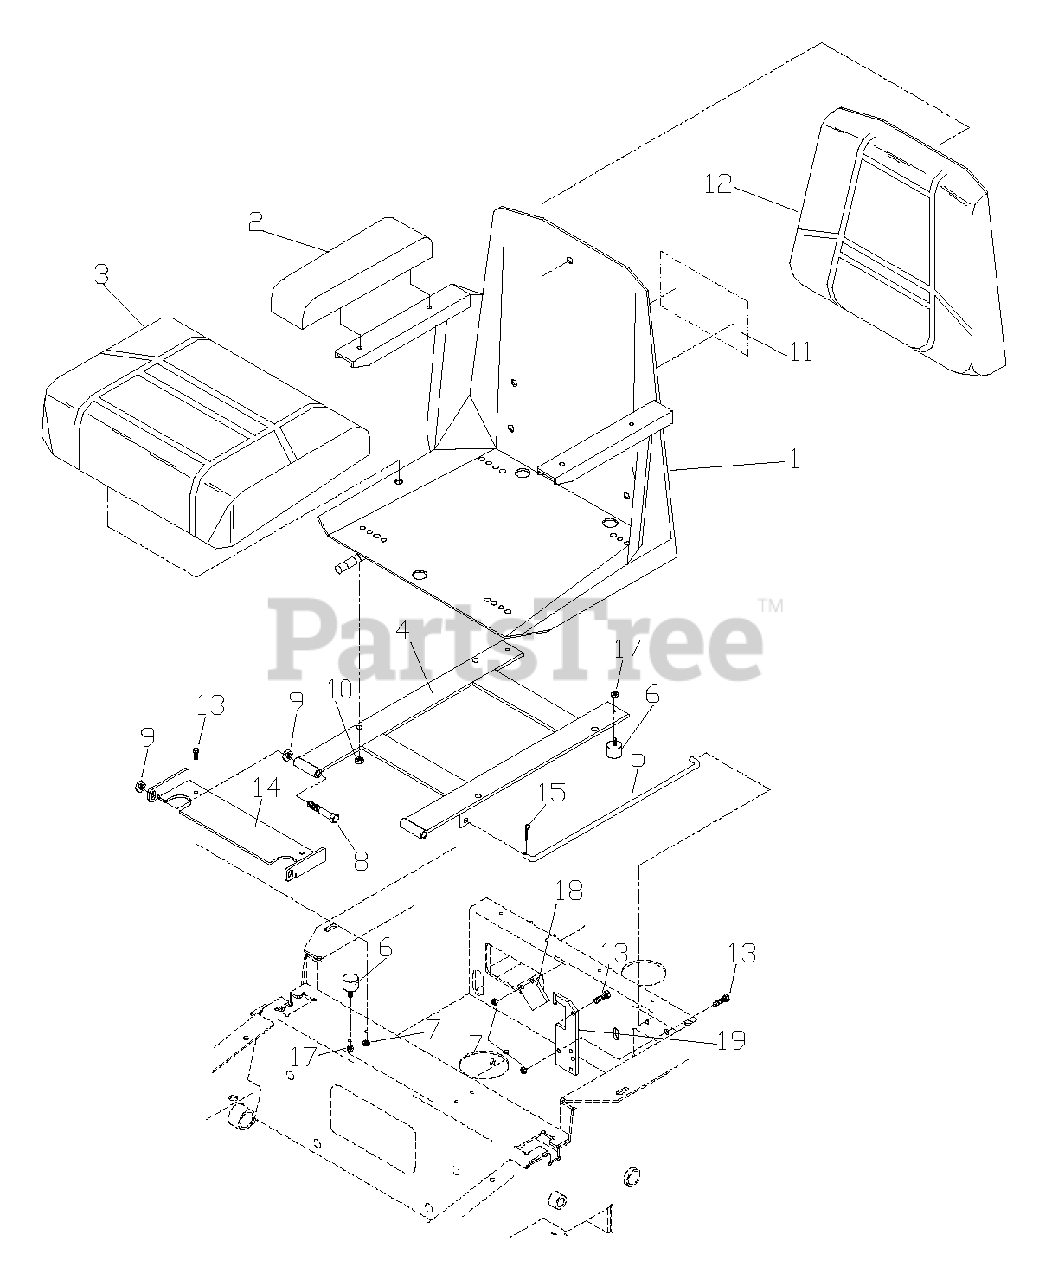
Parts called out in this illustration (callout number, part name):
1	SEAT COMPLETE
2	ARM REST CUSHIONS (1 PAIR)
3	SEAT CUSHION W/SWITCH
4	SEAT MOUNT
7	NUT 1/4 LOCK
8	HCS 3/8 X 3.0
9	NUT 3/8 LOCK
10	NUT 5/16 NYLOC
11	DECAL, CROWN
12	BACK CUSHION
13	HCS 1/4 X 3/4
14	SEAT BRACKET W/DECAL
15	COTTER PIN
17	NUT 1/4 NYLOC
18	SEAT LATCH
19	SEAT LATCH MOUNT
